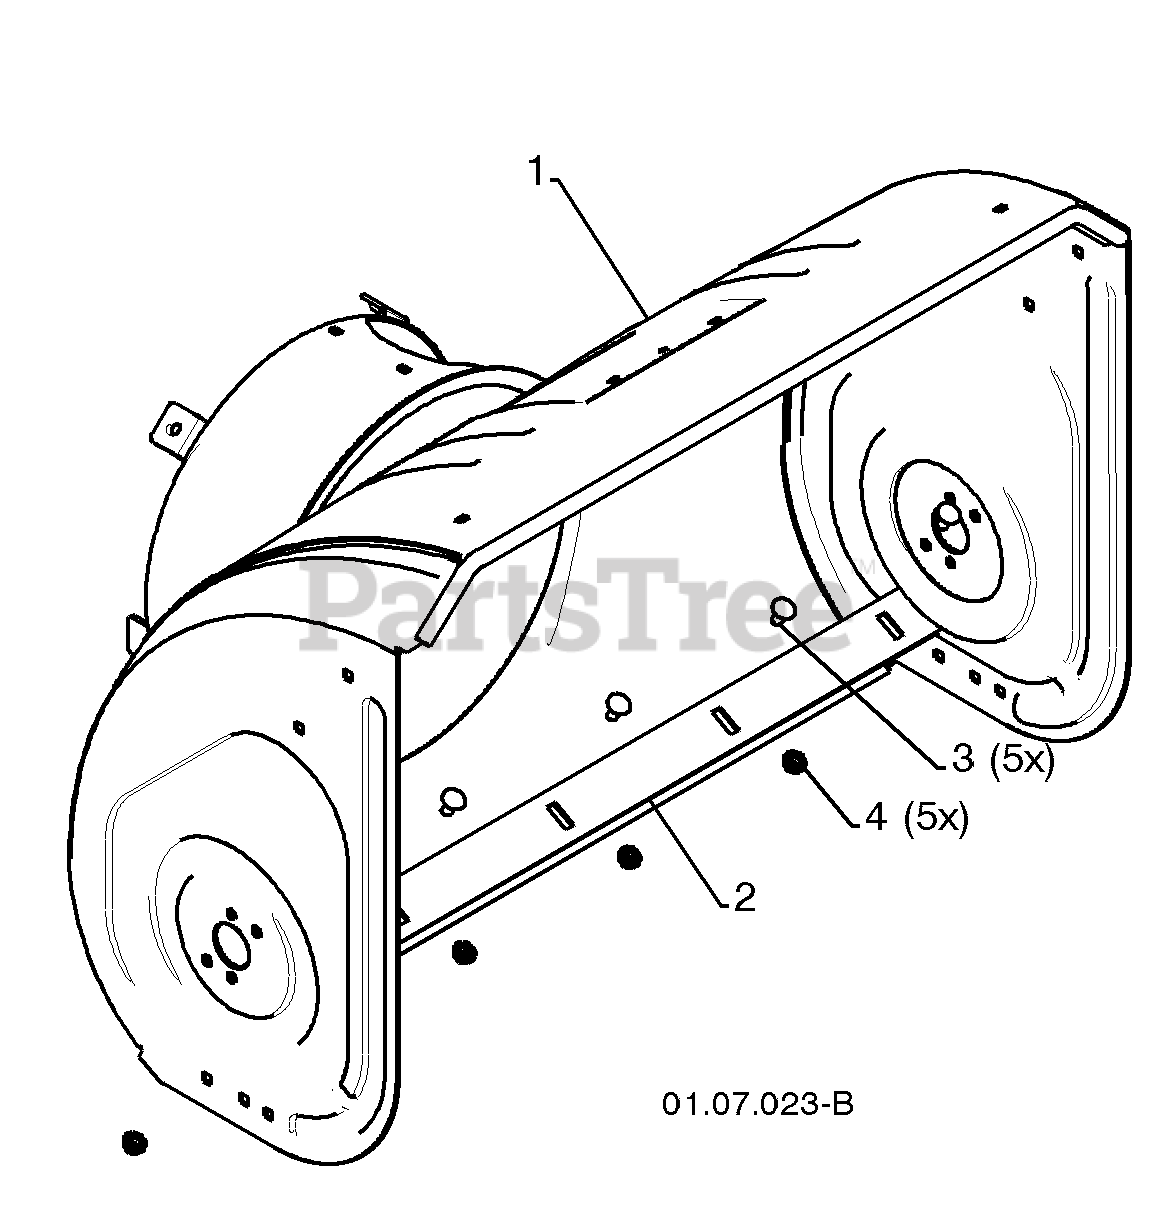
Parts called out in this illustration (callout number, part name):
1	AUGER HOUSING
2	SCRAPPER BAR
3	CARRIAGE BOLT 5/16-18 X .625
4	NUT 5/16-18
